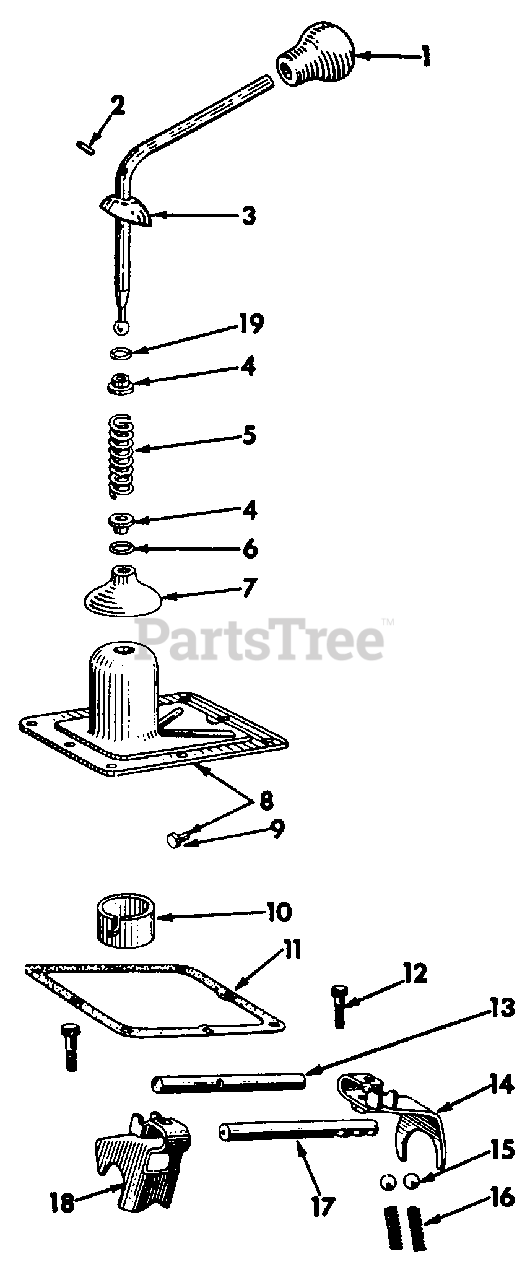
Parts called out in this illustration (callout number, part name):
1	Knob, Gear Shift Lever
2	Pin, Gear Shift Swivel Spring Retainer
3	Lever Assy, Gear Shift
4	Retainer, Gear Shift Swivel Spring
5	Spring, Gear Shift Lever
6	O-Ring, 1/2 X 5/8 X 1/16
7	Shield, Gear Shift Lever
8	Housing Assy, Gear Shift Lever
9	Pin, Gear Shift Lever Swivel Stop
10	Guide, Gear Shift Lever
11	Gasket, Gear Shift Lever Housing
12	Screw, Shifter Fork
13	Shaft, Second & Third Gear Shifter
14	Package, Second & Third Shifter Fork Service
15	Ball, 3/8 Cr-Stl Grade 3
16	Spring, Gear Shifter Poppet
17	Shaft, First & Reverse Gear Shifter
18	Package, First & Reverse Shifter Fork Service
19	O-Ring, 1/2 X 5/8 X 1/16
